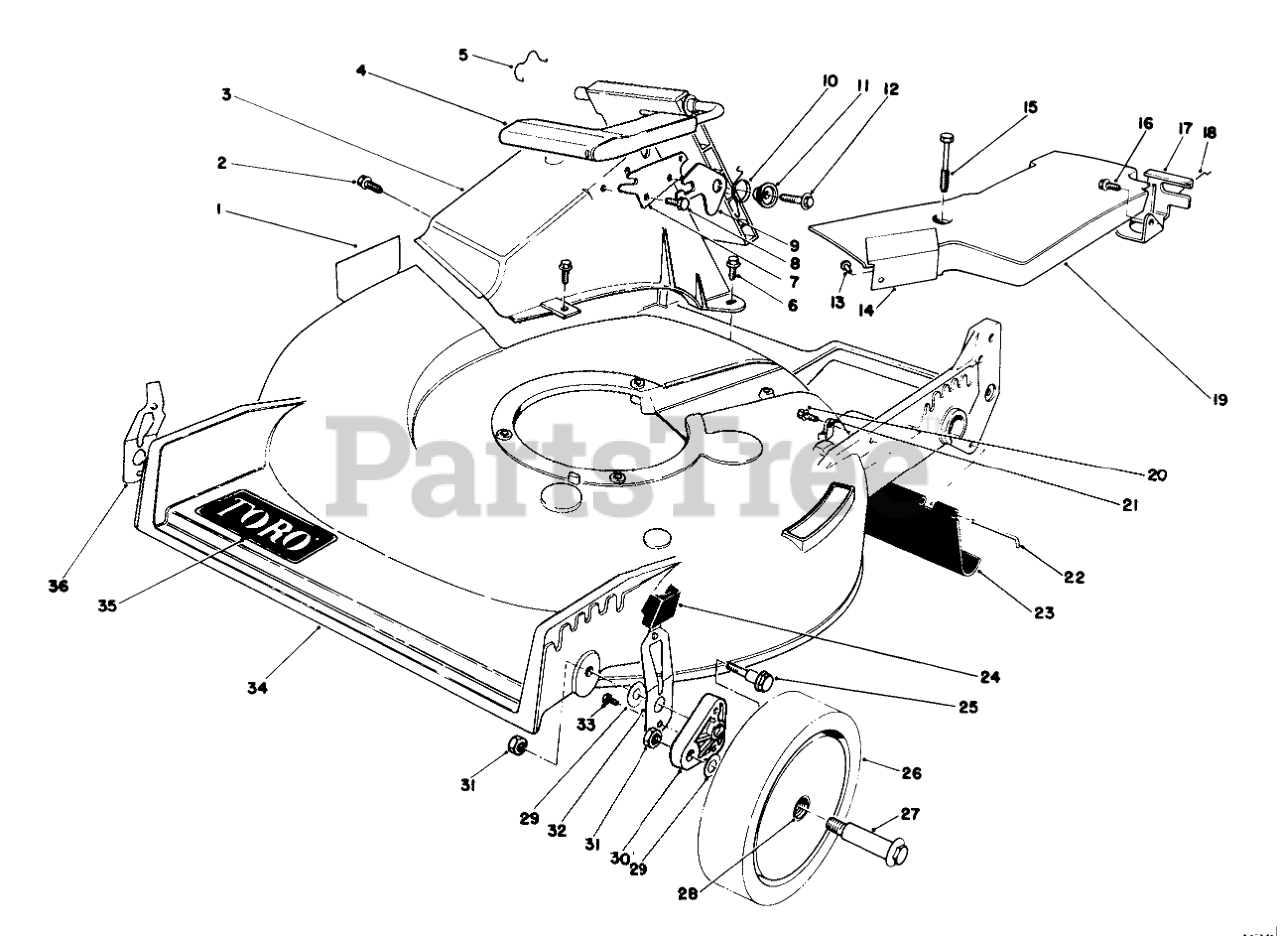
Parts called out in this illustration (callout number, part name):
1	DECAL-DANGER
2	SCREW AND WASHER ASM
3	Tunnel-Discharge (Incl. Ref. #6)
4	Discharge Door Assembly
5	DOOR RET SPRING
6	SCREW-HWH
7	DOOR LATCH PLATE
8	SCREW-PLASTITE
9	SAFETY LATCH
10	TORSION SPRING
11	DOOR SPACER
12	SCREW-HWH
13	RIVET-HEAD, FLAT
14	HEAT SHIELD
15	SCREW-HHFTF
16	SCREW-HWHTF
17	Bracket-Traction Adj.
18	RETAINER-CABLE
19	Belt Cover Assembly (Incl. Ref. #13 & 14)
20	SCREW
21	CLAMP-CABLE
22	ROD-SHIELD
23	SHIELD-TRAILING
24	KNOB-ARM
25	SCREW-SHOULDER
26	Wheel & Tire Assembly (Incl. Ref. #28)
27	WHEEL BOLT
28	BUSHING
29	WASHER
30	ARM-PIVOT, FRONT
31	Nut
32	LH SPRING ARM ASSEMBLY
33	SCREW-HWH
34	Housing (Incl. Ref. #1 & 6)
35	DECAL
36	RH SPRING ARM ASSEMBLY
